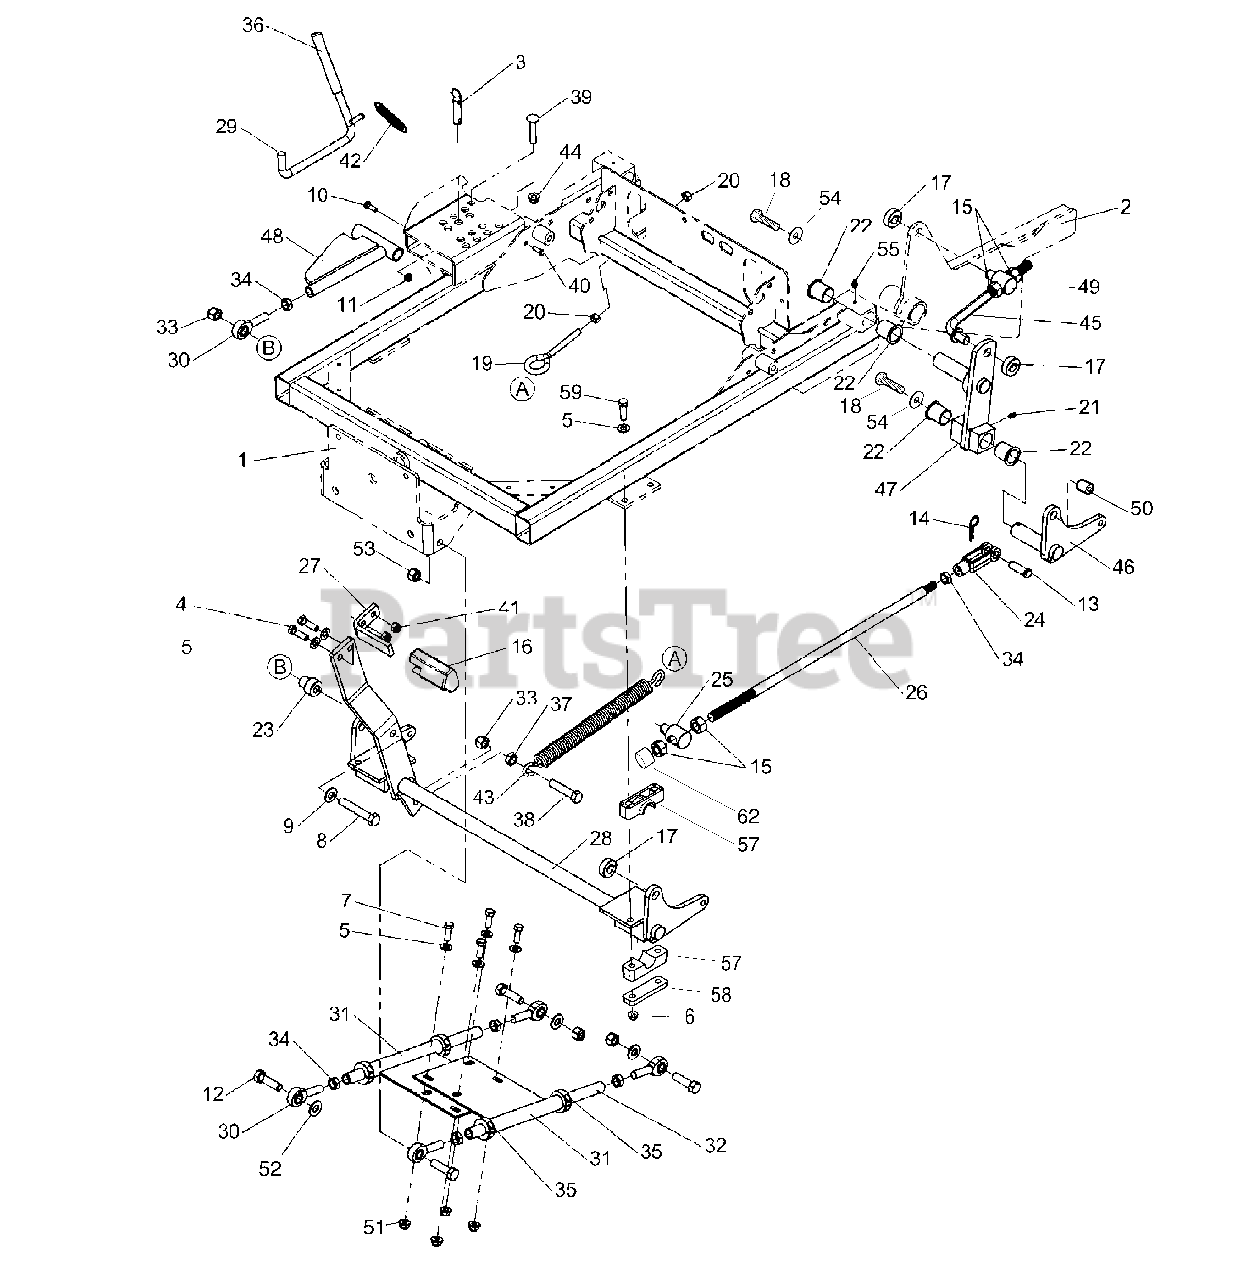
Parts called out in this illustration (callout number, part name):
1	MAIN FRAME
2	MOTOR MOUNT
3	PIN, HITCH, 1/2 X 2.00 OAL, YP
4	CAPSCREW, Hex Head, 3/8-16 x 1-1/4
5	WASHER, 3/8" GR. 9 FLAT
6	NUT, 3/8-16, Hex Flange Nylock
7	CAPSCREW, Hex Head, 3/8-16 x 1
8	BOLT, 1/2-13 X 3 GD5 YZ
9	WASHER, 1/2
10	CAPSCREW, Hex Head, 1/4-20 x 5/8, GR5
11	NUT, Serrated Flange, 1/4-20
12	BOLT, 1/2-20 X 1-3/4" GD5 YZ
13	PIN, CLEVIS, 1/2 X 1 1/2, YZP
14	PIN, Quick, 1-7/8 Lg
15	NUT, Hex, 5/8-11
16	RUBBER, FOOT PEDAL
17	COLLAR, 5/8" SPLIT
18	BOLT, 3/8-16 x 3/4, GD5, YZ WITH PATCH
19	EYEBOLT, 3/8-16 X 5, 2.88 THRD (5021812)
20	NUT, Hex, Full, 3/8-16
21	GREASE FITTING, 1/4-28 STRAIGHT
22	BUSHING, 1.00 X 1.13 X 1.38, PLASTIC
23	ADAPTER, Caster Wheel (2 per tire) (for serial no. 201 & up)
24	CLEVIS, 1/2-20
25	PIVOT, SPRING ROD
26	ROD,DECK LIFT ADJUSTMENT
27	PEDAL, FOOT - BLK
28	DECK LIFT SHAFT
29	WELD, ROD DECK LIFT - BLK
30	BALL JOINT, 1/2-20, MALE
31	WELD, DECK STABILIZER
32	SHAFT, DECK STABILIZER
33	NUT, Hex, Nylon Lock, 1/2-13
34	NUT, Hex Jam, 1/2-20
35	COLLAR, 3/4" SPLIT
36	GRIP, FOAM, .475 X 4.35 X .095
37	NUT, Hex, Jam, 1/2-13
38	BOLT, 1/2-13 X 2-1/4" GD5 YZ
39	BOLT, 3/8-16 X 2, CARRIAGE, GD5, CZ
40	PIN, CLEVIS, 1/4" x 3/4"
41	NUT, Hex, Nylon Lock, 3/8-16
42	SPRING-EXT, .500 OD X 3.50 LG X .058 WR
43	SPRING-EXT, 1.00 ODX13.25LGX.177WR, BLK
44	NUT, Hex, Side Lock, 3/8-16
45	ROD, DECK LIFT
46	DECK LIFT PIVOT, RH
46	DECK LIFT PIVOT, LH
47	ASSM, REAR LIFT - LH - CITATION
47	ASSM, REAR LIFT - RH - CITATION
48	WELD, DECK ADJUST LINK
49	PIVOT, SPRING ROD
50	BUSHING, .510 X .625 X .500
51	NUT, Hex, Serrated Flange, 3/8-16 (S/N 616 & up)
52	WASHER, 1/2" GR. 9 FLAT
53	NUT, Hex, Nylon Lock, 1/2-20
54	WASHER, .390 X 1.50 X .109, YZ
55	GREASE FITTING, 45 DEGREE
56	WASHER, Flat, 3/8
58	PLATE, PIVOT BLOCK SUPPORT - BLK
59	CAPSCREW, Hex Head, 3/8-16 X 2-3/4
62	CAP, VINYL - .562 X .750 - BLK
